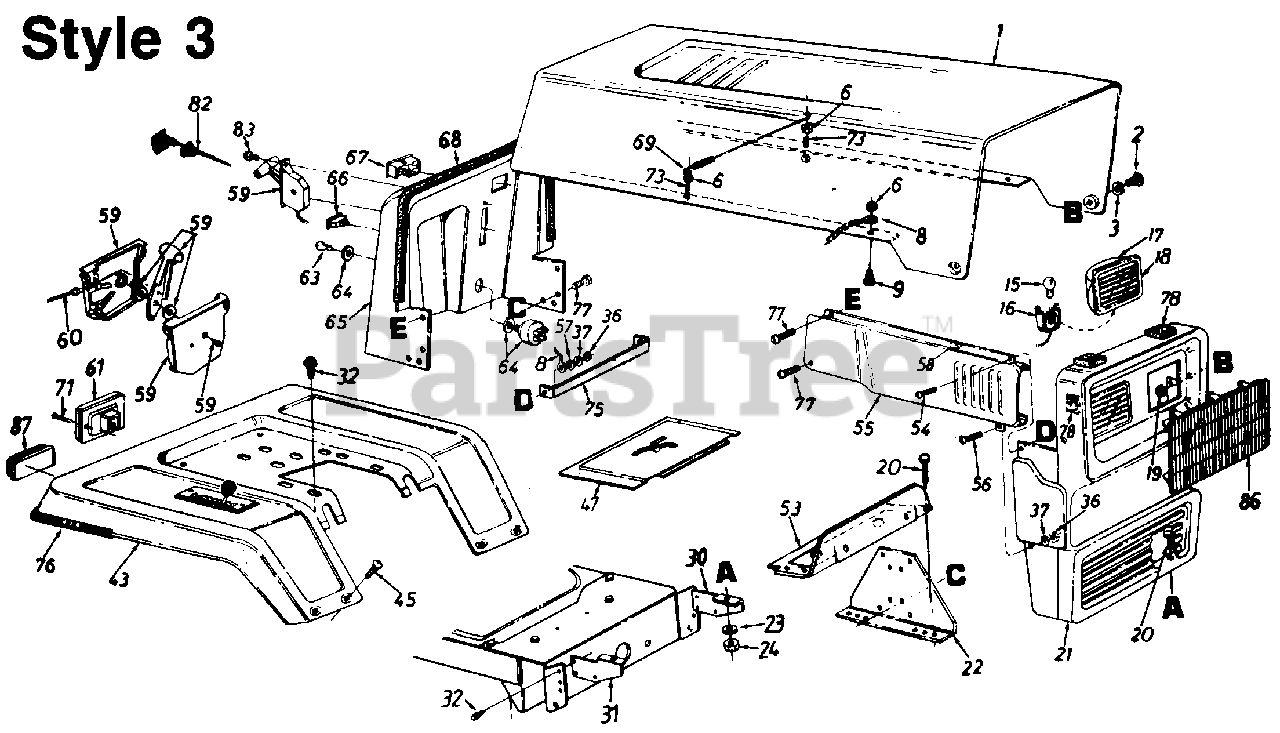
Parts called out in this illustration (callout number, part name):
3	Washer.39" I.D. x .62"
6	Hex Sems Nut #10-24 Thd.
8	Hood Stop
9	Truss Hd. Scr. #10-24 x 1/2"
15	Lamp
16	Twist Lock-Lamp Socket
17	Headlight Housing
18	Lens
19	L-Nut 1/4-28 Thd.
20	Hex Bolt 5/16-18 x .75" Lg.
23	L-Wash. 5/16" I.D.
24	Hex Nut 5/16-18 Thd.*
30	Grille Mount Brk't.-L.H.
36	Hex Nut 1/4-20 Thd.
37	L-Wash. 1/4" I.D.
45	Carriage Bolt 1/4-20 x .50
47	Transmission Panel
53	Fuel Tank Support
54	Truss Hd. Scr. 1/4-20 x .75"
55	Side Cover-R.H.
57	Fl-Wash. .281" I.D. x .73" O.D.
58	Mounting Clamp
59	Throttle Control Box Ass'y.
60	Throttle Control Wire
61	Taillight
63	Ignition Key
64	Ignition Switch
67	Ammeter
68	Trim Strip-31"
69	Hood Spring
71	Truss Hd. AB-Tap Scr. #6 x .62" Lg.
73	Hex Scr. #10-24 x 1.0" Lg.
75	Tie Strap-Grille/Side Panel
76	Trim Strip-81"
77	Hex Wash. Hd. Tap Scr. 1/4 x .75" Lg.
78	Foam Strip 3/8 x 1-1/8" x 11/2" Lg.
82	Choke Control 29" Lg.
83	Truss Mach. AB-Tap Scr. #10 x .5" Lg.
86	Headlight Bezel
87	Reflector
